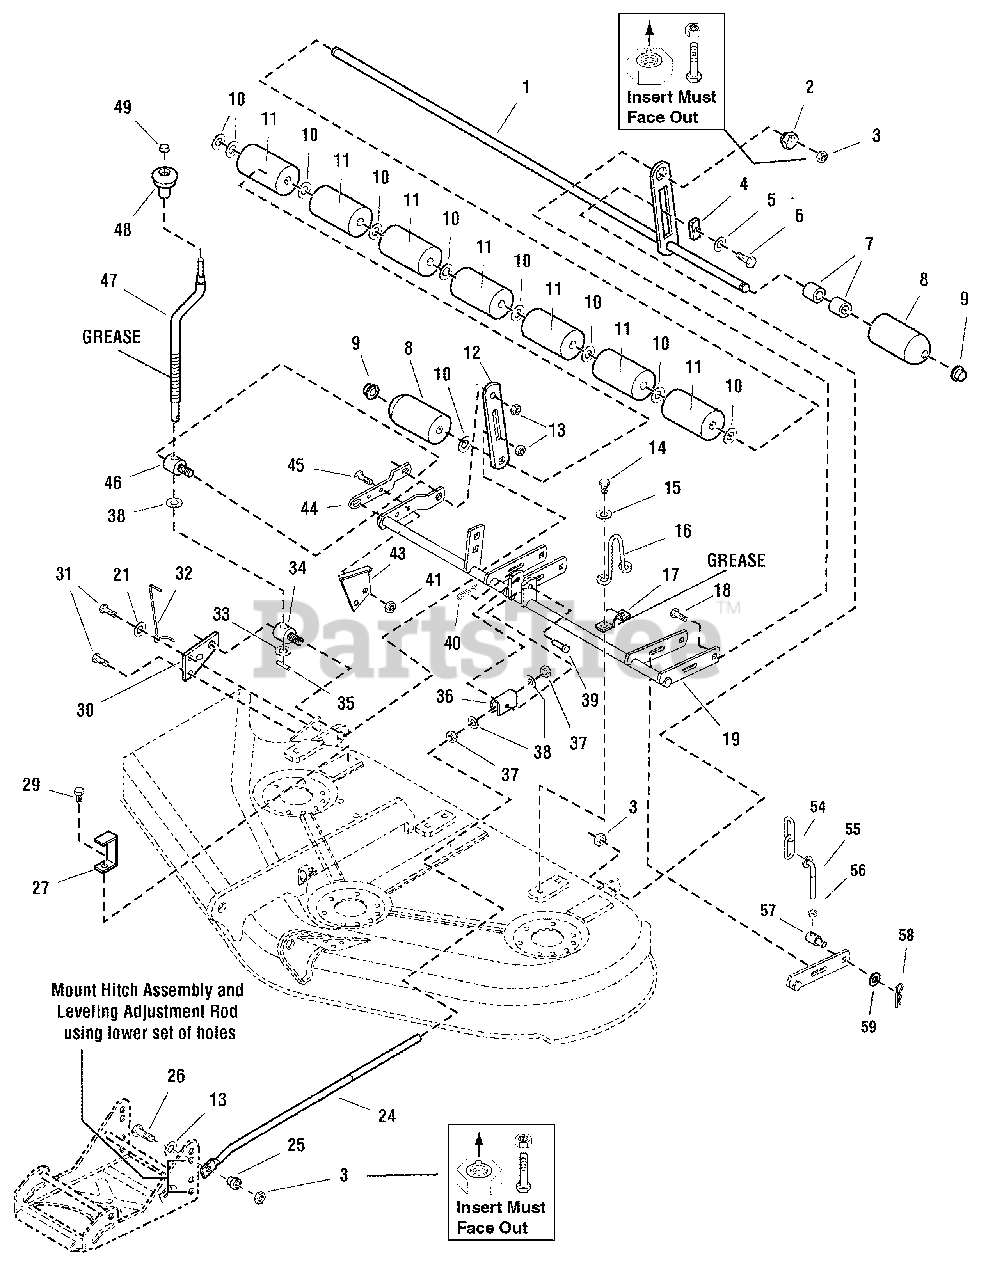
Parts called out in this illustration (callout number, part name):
1	SHAFT ASSEMBLY, Roller, 44", (Includes Ref. Nos. 7 & 9)
2	NUT, Hex Adjusting, .99 DIA .687
3	NUT, Hex Aluminum Insert Lock, 3/8-16
5	WASHER, Plain, 1/2
6	BOLT, Shoulder, 3/8-16 X 1.34
7	SPACER, .66 ID
8	ROLLER, Rounded, 2-1/2 Long
9	NUT, Push
10	WASHER, 5/8
12	BAR, Roller
13	NUT, Hex, Flange, Lock, 1/2-13
14	CAPSCREW, Hex Head Taptite, 5/16 -18 x 3/4
15	WASHER, 3/8
16	UP-STOP, 6-1/4 High, Black
17	STRAP, Mower Arm Assembly
18	CARRIAGE BOLT, 3/8-16 x 1-1/2
19	ARM ASSEMBLY, Mower
21	WASHER, 5/16, Black
24	ROD, Adjustment
25	SPACER, 3/8 x 3/4 x 15/16
26	CAPSCREW, Hex Head, 3/8-16 x 1-3/4
27	BRACKET, Up-Stop, 6" Long
29	CAPSCREW, Hex Washer Head Taptite, 5/16-18 x 3/4, Black
30	PLATE, Mower Support
31	CAPSCREW, Hex Head Taptite, 5/16-18 x 1-1/4
32	INDICATOR, Cutting Height
33	WASHER, Detent
35	PIN, Roll, 1
37	NUT, Hex, Jam, 1/2-13
38	WASHER, 33/64
39	PIN, Clevis
40	CLIP, Hair Pin
41	NUT, Whiz Lock 5/16-18
43	BRACKET, Cutting Height
44	ARM, Rear, Mower, RH
45	CAPSCREW, Hex Head, 5/16-18 x 1-1/4
46	TRUNNION, Threaded
47	CRANK, Cutting Height
48	KNOB, Height Crank
49	PAL NUT
54	CHAIN, 2-Link
55	ROD, Height Adjustment
56	NUT, Hex Jam
58	CLIP, Hair Pin
59	WASHER, 3/8
